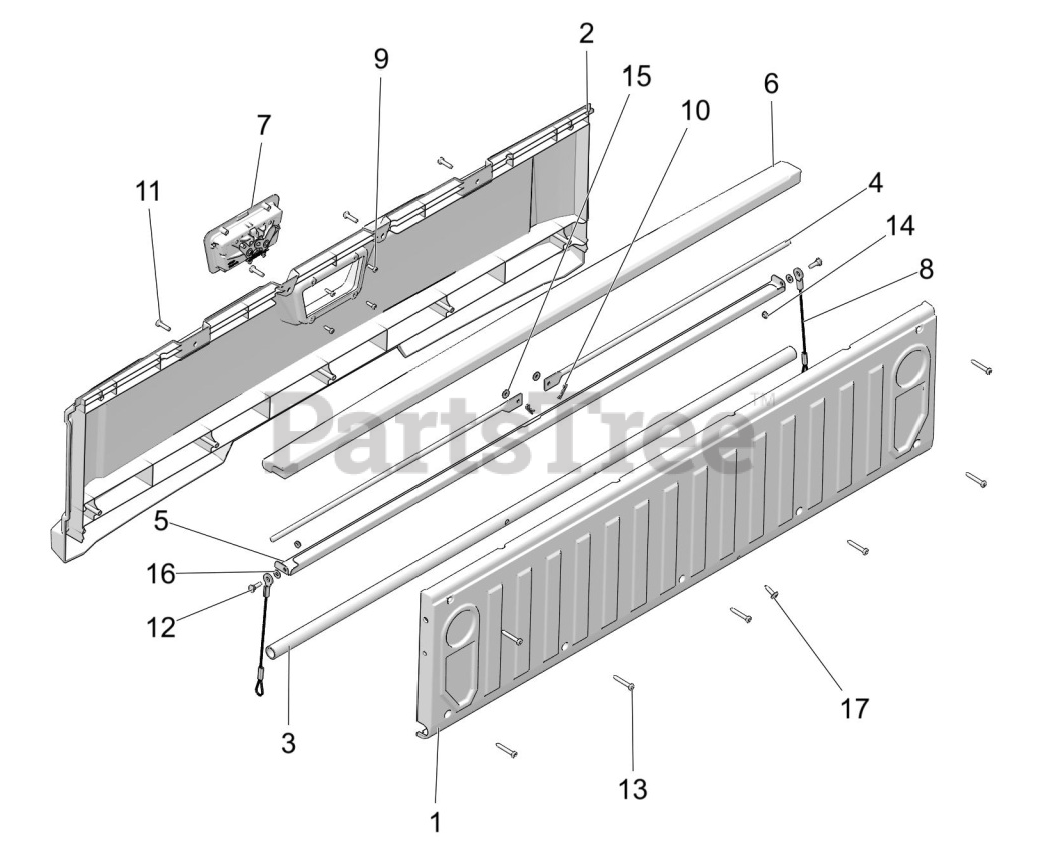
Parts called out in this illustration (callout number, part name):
1	PANEL, TAILGATE INNER BLACK
2	PANEL-TAILGATE,OUTER,BLK
3	TUBE-TAILGATE PIVOT,BLK
4	ROD, TAILGATE
5	BRACKET, TAILGATE
6	CAP, TAILGATE BLACK
7	LATCH, PADDLE
8	CABLE, TAILGATE
10	PIN, HITCH
11	SCR-#14X1 HI/LO-PH-PN TRX-M
12	BLT-SHLDR .188X.188X.25-20
14	NUT, HEX
16	WASHER, FLAT
